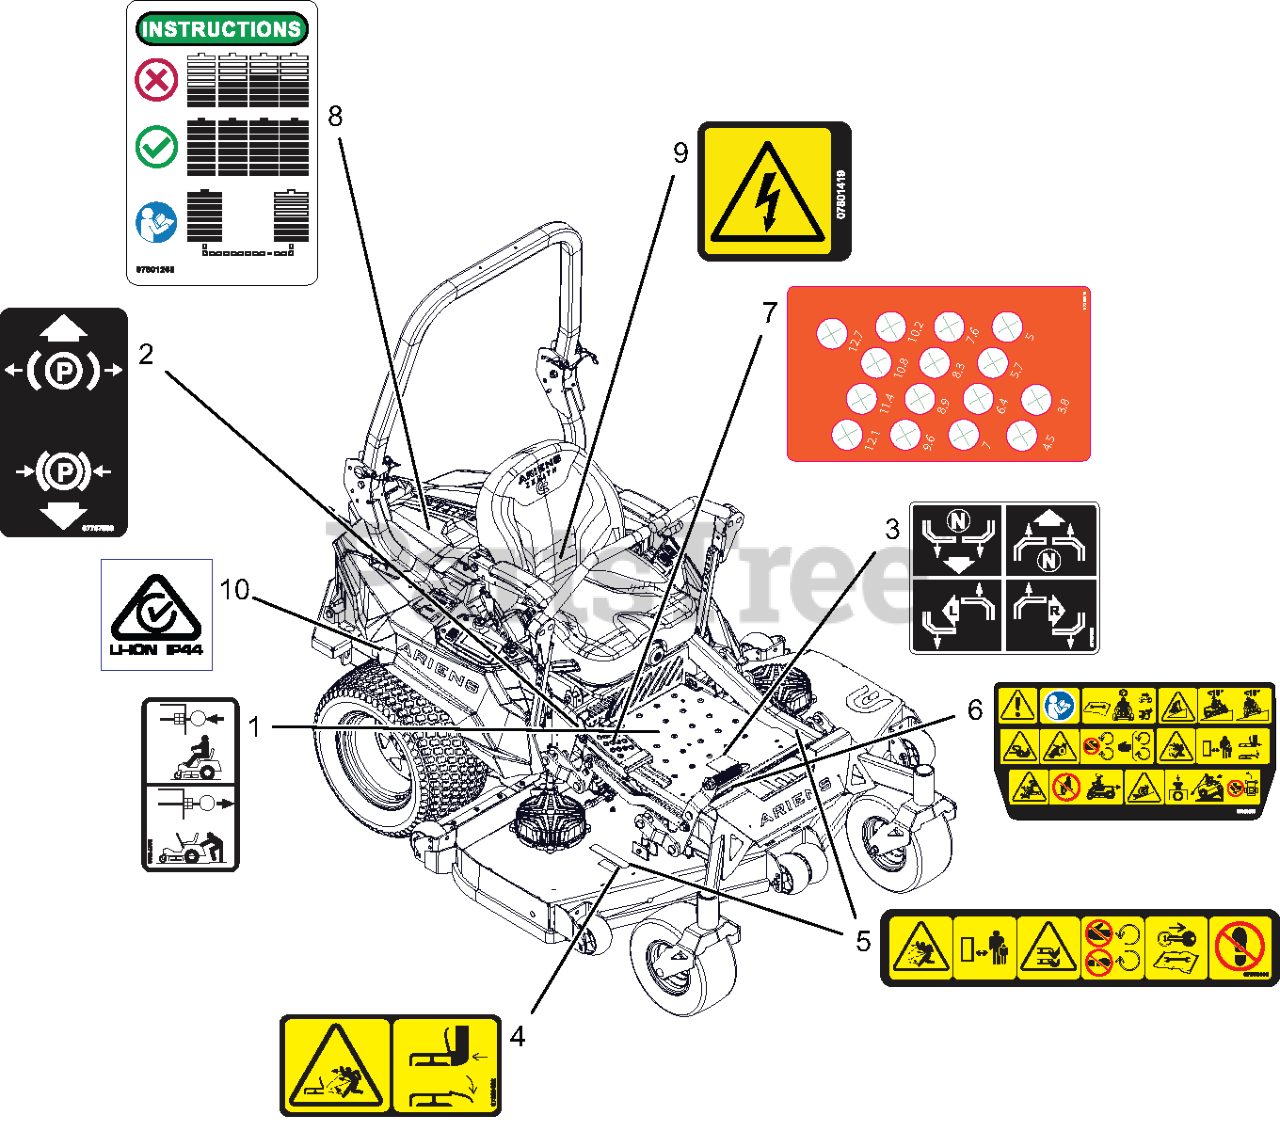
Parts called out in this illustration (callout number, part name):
1	DECAL, TRANSMISSION DISCONNECT
2	DECAL, PARKING BRAKE LEVER
3	DECAL, INSTRUCTIONAL-STEERING
4	DECAL, SAFETY - DECK GUARDING
5	DECAL, DECK SAFETY
6	DECAL, MAIN SAFETY
7	DECAL, APEX HOC METRIC
8	DECAL, BATTERY BALANCE
9	DECAL, SAFETY - DANGER
10	DECAL, LI-ION IP44
